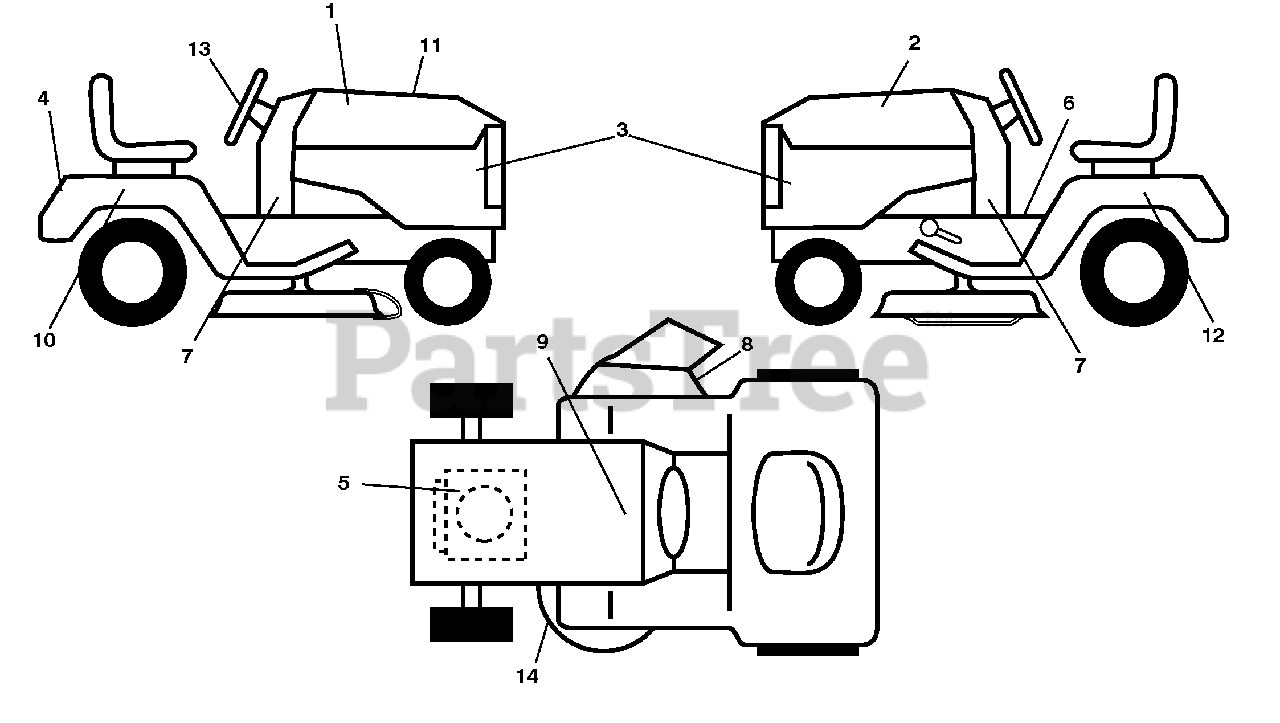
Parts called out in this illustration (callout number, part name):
1	Decal, Hood RH
2	Decal, Hood LH
3	Decal, Side Panel
4	Decal, Fender
5	Decal, Eng H.P.
6	Decal, Fender Operator's
7	Decal, Lower Dash
8	Decal, Warning
9	Decal, Battery Dnge/Poi
10	Decal, Fender SD RH
11	Decal, Replacement
12	Decal, Fender SD LH
13	Decal, Steering Wheel
14	Decal, Mower Schematic
14	Pad, Footrest Control
14	Decal, Bypass
14	Pad, Footrest, LH
14	Manual, Operator's (Eng/French)
14	Manual, Parts (Eng/French)
